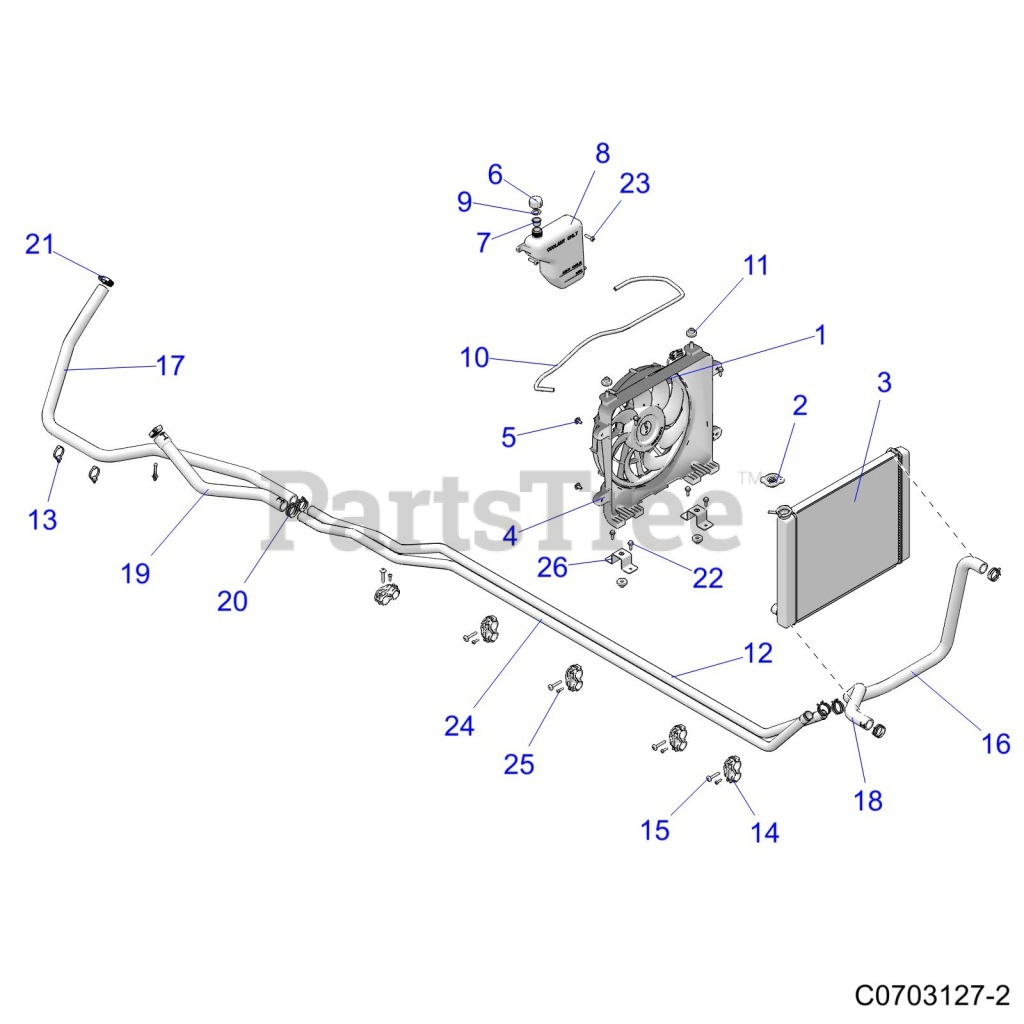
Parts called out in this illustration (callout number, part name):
1	ASM., RADIATOR [INCL. 2-5]
3	ASM., RADIATOR, CORE
4	FAN, ASM.
5	BOLT-M6X15MM
6	CAP, OVERFLOW
7	CAP,PLUG9X(GRN),FLEX TEMP(10)
8	TANK-SURGE
9	GASKET (10)
10	FUEL LINE-95 CENTIMETERS
12	TUBE-COOLANT
13	CLIP-ROUTING
14	CLIP-COOLANT ROUTING
16	HOSE-UPPER,RAD
17	HOSE-ENGINE,OUT,GAS
18	HOSE-LOWER,RAD
19	HOSE-ENGINE,IN
20	CLAMP,SPRINGBAND 35/12,BLK
21	CLAMP-HOSE(WORM DR)25-40MM
22	SCR-M6X1.0X20,HXHD,FLG,TDFM,BL
23	SCR-#14X1 HI/LO-PH-PN TRX-M
24	TUBE-COOLANT
26	BRKT-RADIATOR MNT,LWR,BLK
